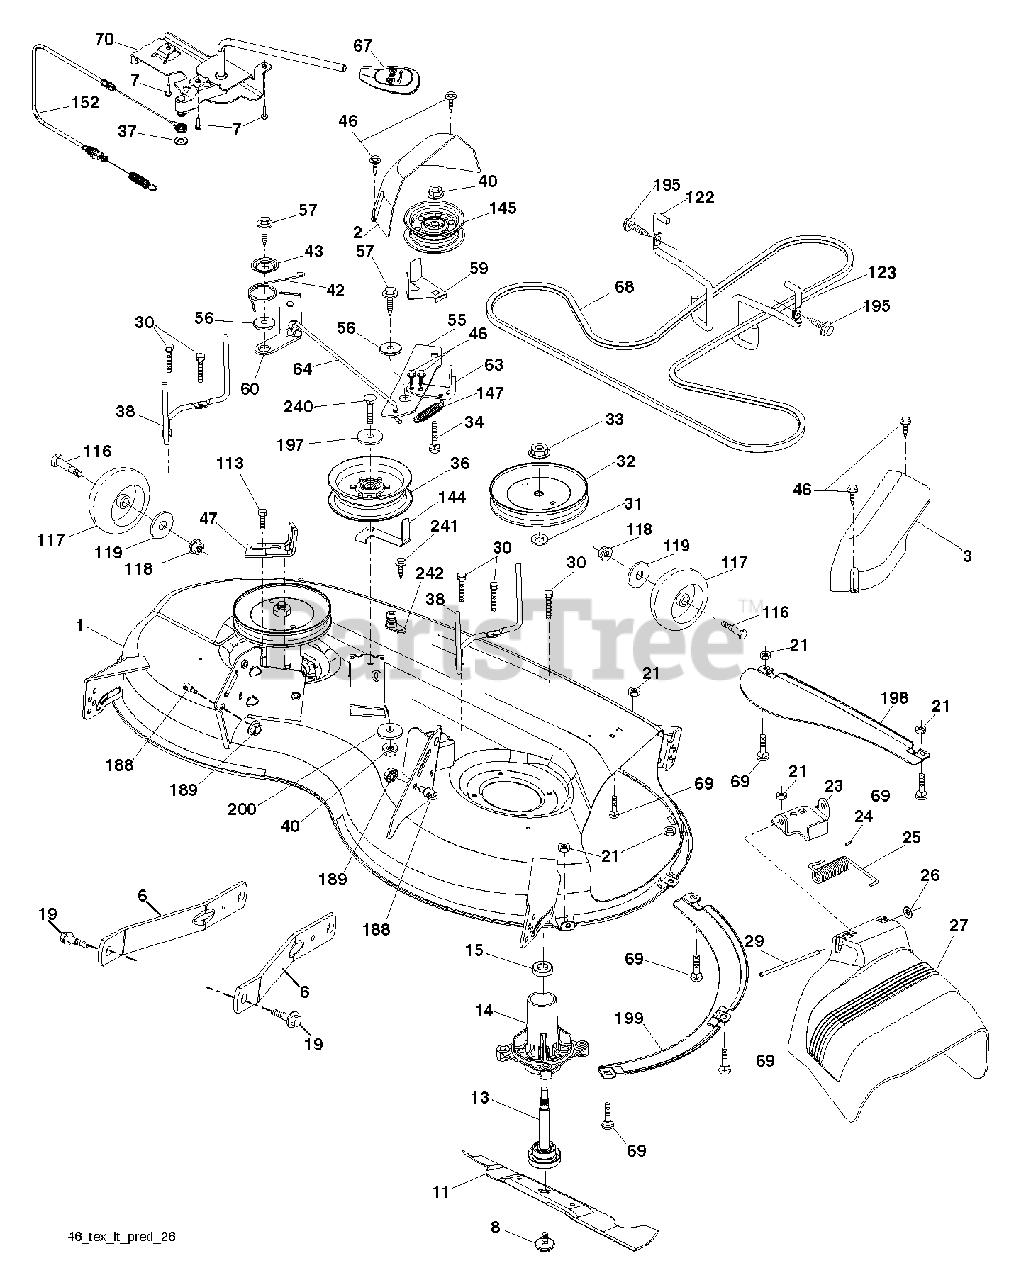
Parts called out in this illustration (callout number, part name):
1	Mower Deck Weldment, 46"
2	COVER.MANDREL.LH.46"
3	COVER.MANDREL.RH.46"
6	ARM.SUSPENSION.MOWER.R
7	SCREW.#10 X 0.750.BOS (2 2)
8	BOLT.WASHER.ASM.7/16-2
11	BLADE.MOWER.46".HI.LIFT
13	SHAFT.ASM.MDRL.N/GREASE.38
14	HOUSING.MANDREL.4PT.
19	BOLT.SHOULDER
21	LOCKNUT
23	BRKT.DEFLECTOR.38"2005+
24	CAP-SLEEVE LT
25	SPRING.TORSION.DEFLECT
26	NUT PUSH M
27	SHIELD.DEFLECTOR.MOWER.46"BLK
29	ROD.HINGE
30	SCREW, WASHER HEAD
31	WASHER.SPACER.MANDREL
32	PULLEY.MANDREL.5.438.PD
33	NUT.FLANGE.LOCK.TOP
34	BOLT.3/8-16X1.50
36	PULLEY.IDLER.2006
38	KEEPER.BELT.MANDREL.PULLEY
40	NUT LOCK FLG 3/8-16 UNC
42	SPRING.TORSION.BRAKE
43	SRPING.TORSION.RETAINE
46	SCREW.1/4-20X5/8
47	BRKT.CLUTCH.CABLE
55	IDLER.ARM
56	SPACER.RETAINER
57	SCREW 3/8-16X1
59	GUARD, BELT
60	ARM BRAKE MOWER RH 38"
64	LINKAGE BRAKE
67	HANDLE.CLUTCH.CABLE.LT
68	V-BELT
69	BOLT
70	CLUTCH.ASM.MANUAL
113	BOLT.5/16HEX.WHS.HD
116	BOLT M
117	WHEEL.GAGE.HALF.SPOKED
118	LOCKNUT
119	WASHER
122	KEEPER BELT ENGINE LH
123	KEEPER BELT RH
144	KEEPER.BELT.MOWER
145	PULLEY.IDLER.48"PRIMARY
147	SPRING RETURN
152	CABLE.CLUTCH.MANUAL.
188	STUD.FASTNER.W/ANTI-ROTATE
189	NUT LOCK HEX FLANGE 5/16-18
195	SCREW, 3/8-16X3/4
197	WASHER
198	BAFFLE CENTER FRONT
199	BAFFLE FRONT RH
200	WASHER.13/32 X 1 X 1/2.11GUARD
240	BOLT-HEX EAK
241	SCREW.TT.#10-32X.5.3/8.FLANGE
242	PORT.WASHOUT
